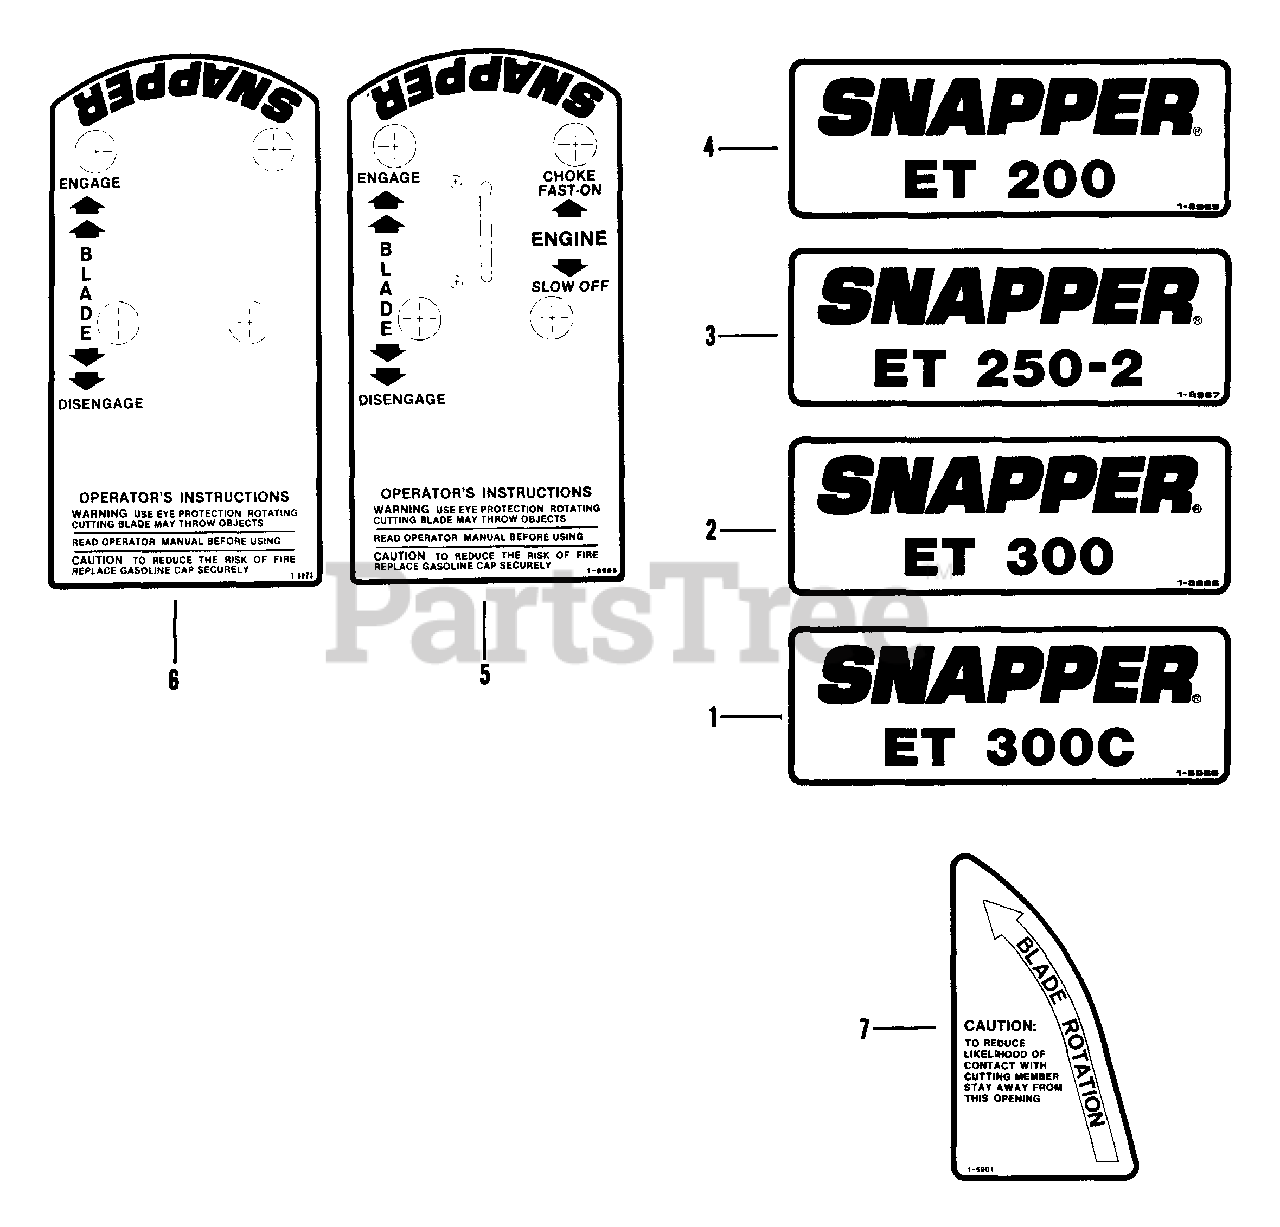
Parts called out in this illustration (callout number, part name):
1	DECAL - ET300C
2	DECAL - ET300
3	DECAL - ET250-2
4	DECAL - ET200
5	DECAL - Control Panel
6	DECAL - Control Panel (2 Cycle)
7	DECAL - Blade Guard
